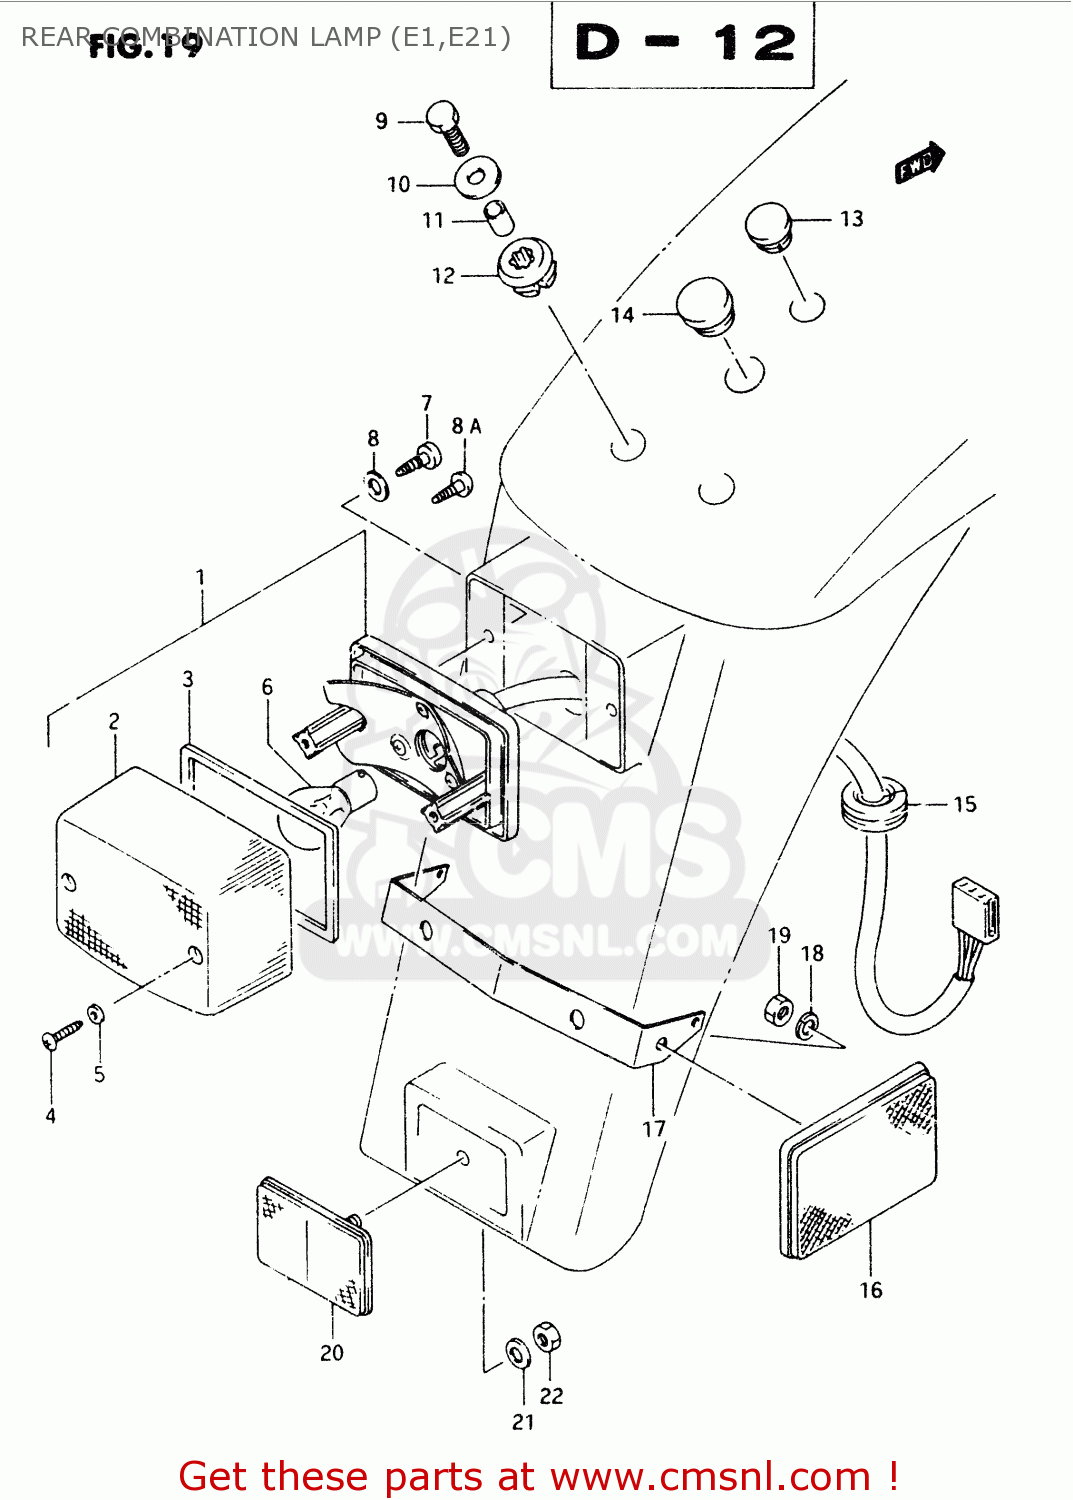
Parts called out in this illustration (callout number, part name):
1	LAMP ASSY, REAR COMBINATION
2	LENS
3	GASKET,RR COMBI LAMP LENS (NAS)
4	SCREW
5	GASKET (NAS)
6	BULB 12V21/5W
7	SCREW
8	WASHER
8A	SCREW
9	BOLT
10	WASHER (6.5X20X1.2)
11	SPACER (6.4X9X10.5)
12	CUSHION
13	PLUG(OD:19)
14	PLUG(OD:22)
15	GROMMET
16	REFLEX REFLECTOR
17	BRACKET
18	WASHER,LOCK
19	NUT ,5MM
20	REFLEX REFLECTOR,RR
21	WASHER
22	NUT
